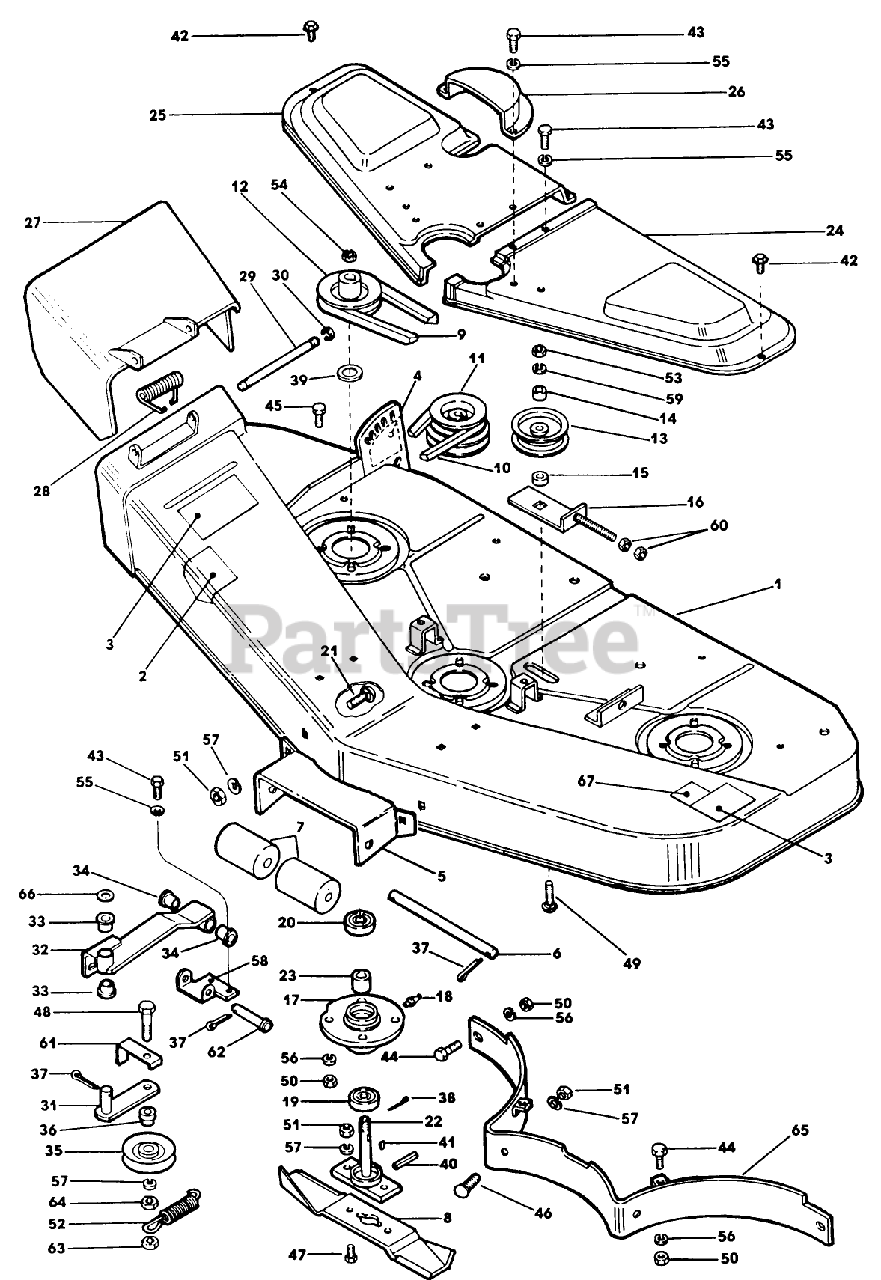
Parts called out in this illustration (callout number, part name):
3	DECAL
6	SHAFT
7	ROLLER
9	V-BELT (DECK)
10	V-BELT (DRIVE)
13	PULLEY - IDLER
14	SPACER
17	HOUSING,SPINDLE S
22	SPINDLE ASSEMBLY *N/P
25	COVER AY - RH
26	Guard, Drive Belt
29	SHAFT - CHUTE
30	E-RING
32	PVT AY-IDLER W/BSH *G
33	BUSHING
34	BUSHING
35	PULLEY - V-IDLER
36	SPACER
39	SPACER
42	SCREW-THREAD FRMG
43	SCREW-HH
44	SCREW - HEX
45	SCREW
46	BOLT - CARRIAGE
48	SCREW-HH
49	BOLT - CARRIAGE
50	NUT SS
51	NUT
52	SPRING - TENSION *B
53	NUT - HEX JAM
54	NUT-BLADE SPINDLE
57	WASHER
59	WASHER
62	PIN - CLEVIS
63	NUT
64	NUT-HEX JAM
66	SPACER
